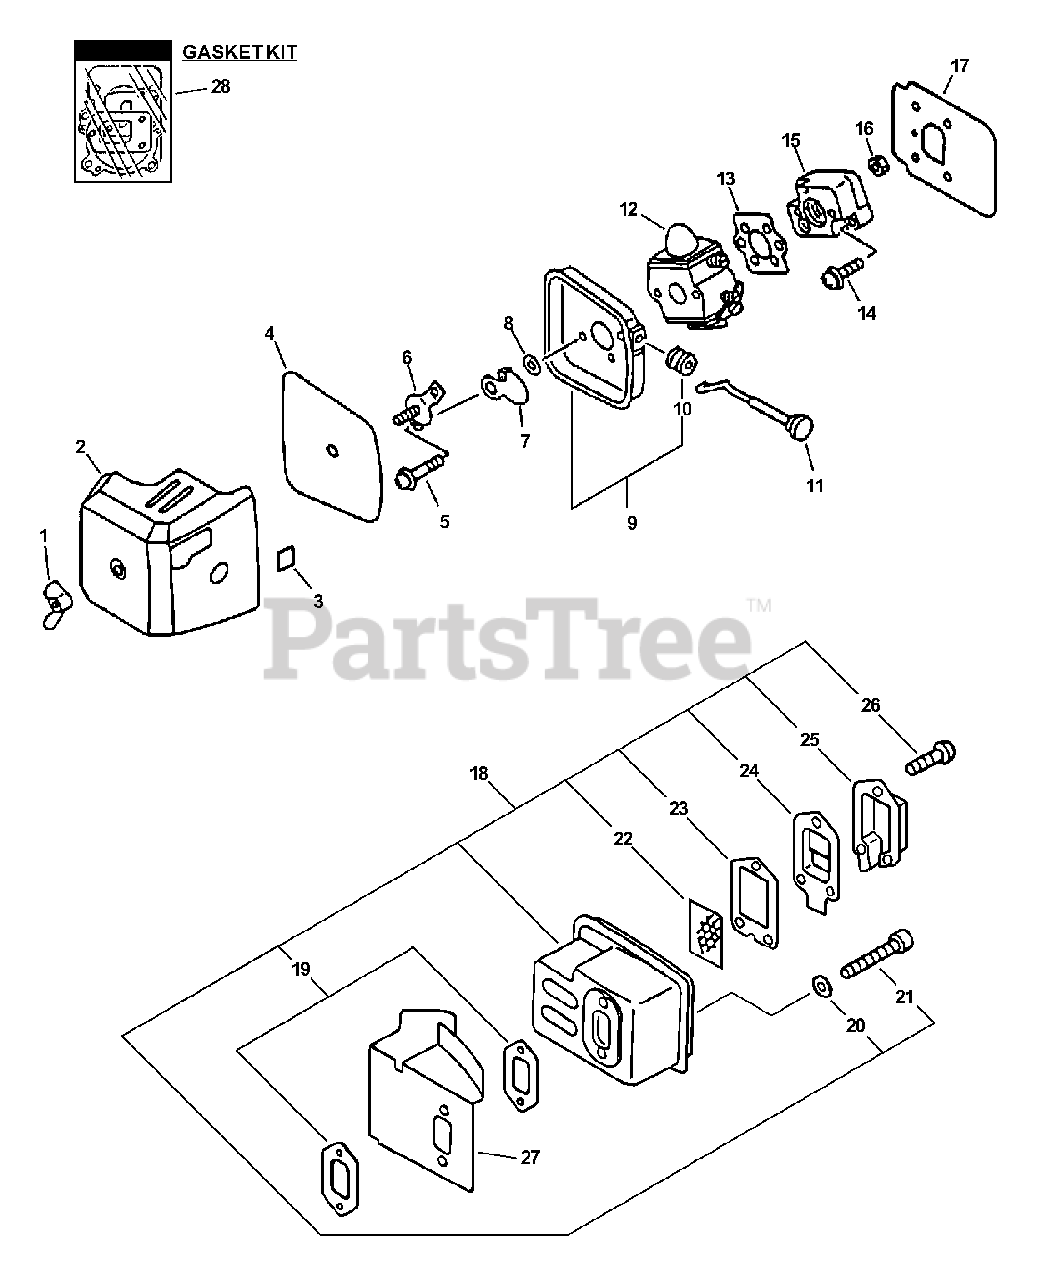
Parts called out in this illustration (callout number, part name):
1	WINGNUT - 6
2	COVER, AIR FILTER
3	LABEL, CHOKE
4	FILTER, AIR
5	SCREW 5×57
6	PLATE, PREVENT
7	SHUTTER, CHOKE
8	WASHER 5.2×8×0.8T
9	CASE, AIR FILTER
10	GROMMET, CHOKE
11	ROD, CHOKE
12	CARBURETOR - C1U-K54
12	CARBURETOR - C1U-K54A
13	GASKET, INTAKE
14	SCREW 5×20
15	INSULATOR, INTAKE
16	NUT M5
17	HEAT SHIELD, INTAKE
18	MUFFLER ASSY
19	GASKET, EXHAUST
20	WASHER, FLAT 5.5×10×0.8
21	BOLT M5×50
22	SCREEN, SPARK ARRESTER
23	GASKET, EXHAUST
24	GUIDE, EXHAUST
25	GUIDE, EXHAUST - INNER
26	SCREW 4×10
27	COVER, MUFFLER
28	GASKET KIT
